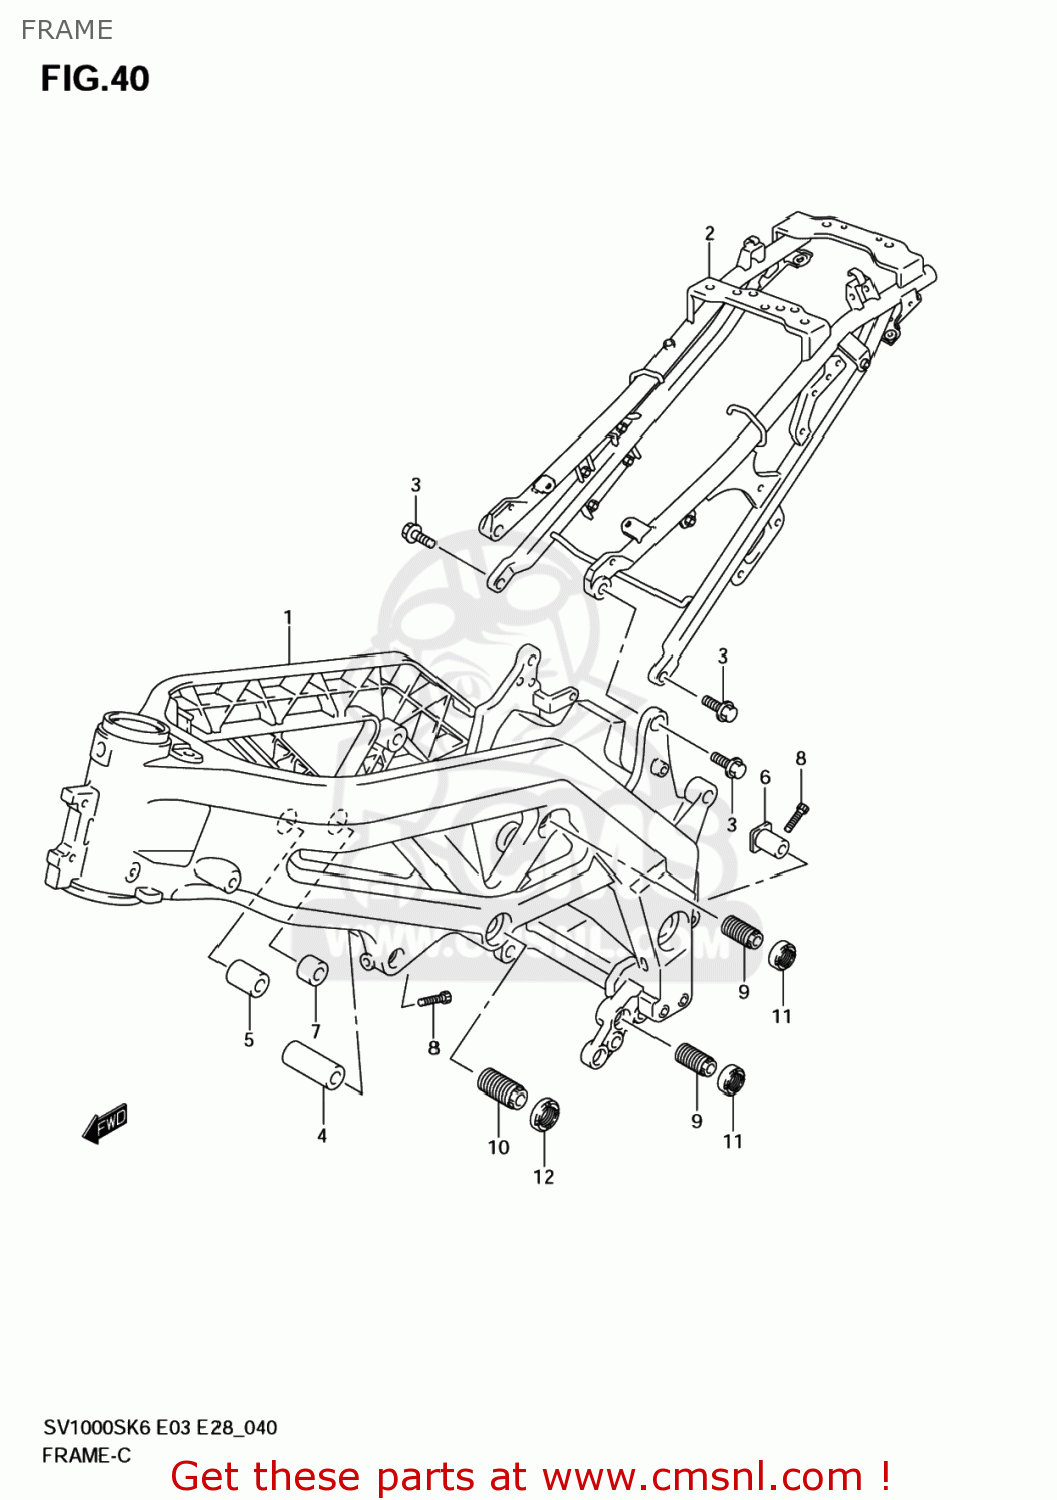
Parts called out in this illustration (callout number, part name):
1	FRAME(BLACK)
2	RAIL,SEAT(BLACK)
3	BOLT,SEAT RAIL
4	SPACER,ENG HEAD MTG FR,L
5	SPACER,ENG HEAD MTG RR,R
6	SPACER,MOUNTING RR UPR,R
7	SPACER,ENG HEAD MTG CTR,R
8	BOLT(8X32)
9	BOLT,CASE LWR & RR HEAD ADJ
10	BOLT,CRANK CASE ADJUST CTR
11	NUT,CRANK CASE ADJUST BOLT
12	NUT,CRANKCASE ADJUST
